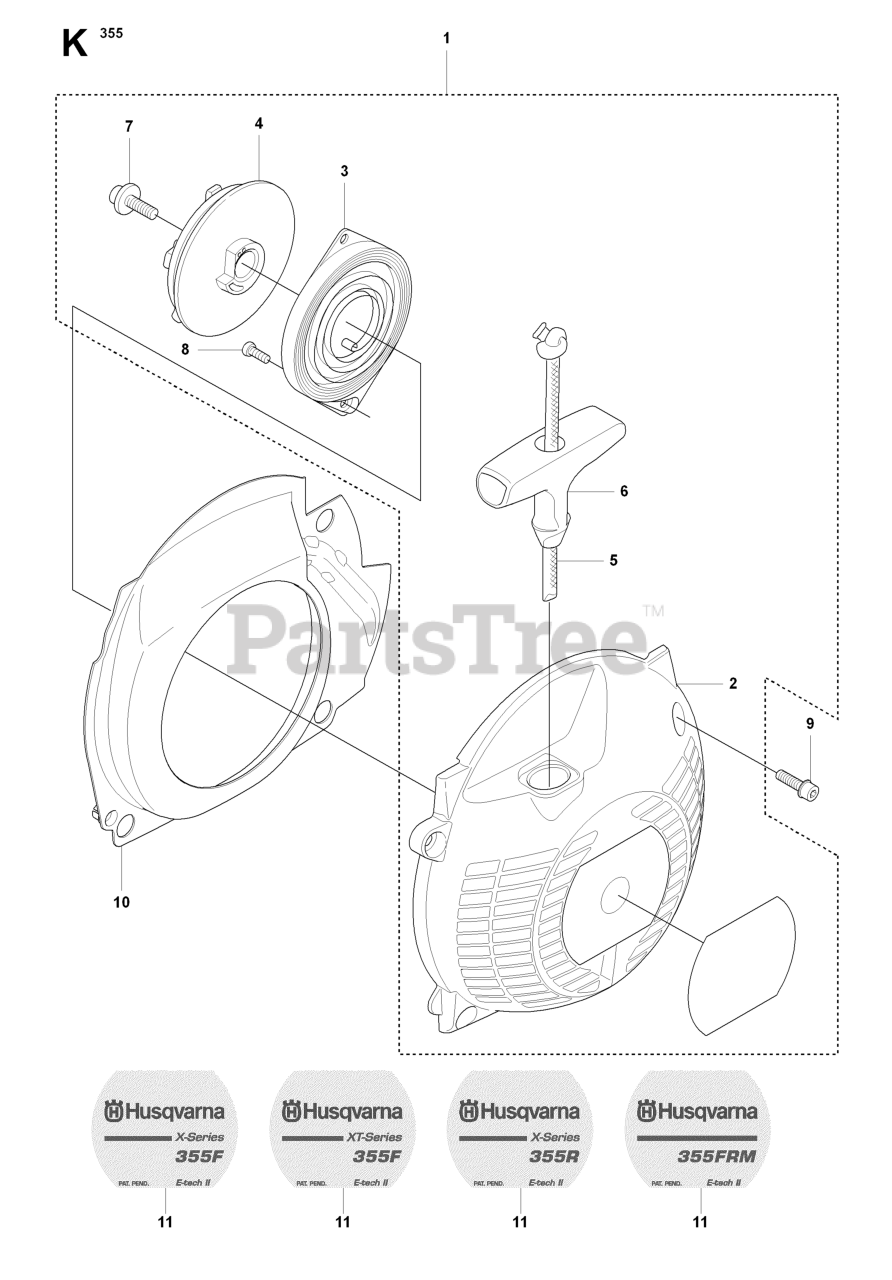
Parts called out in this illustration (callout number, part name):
1	STARTER
2	STARTER HOUSING
3	RECOIL SPRING
4	STARTER PULLEY
5	STARTER ROPE
10	AIR CONDUCTOR
